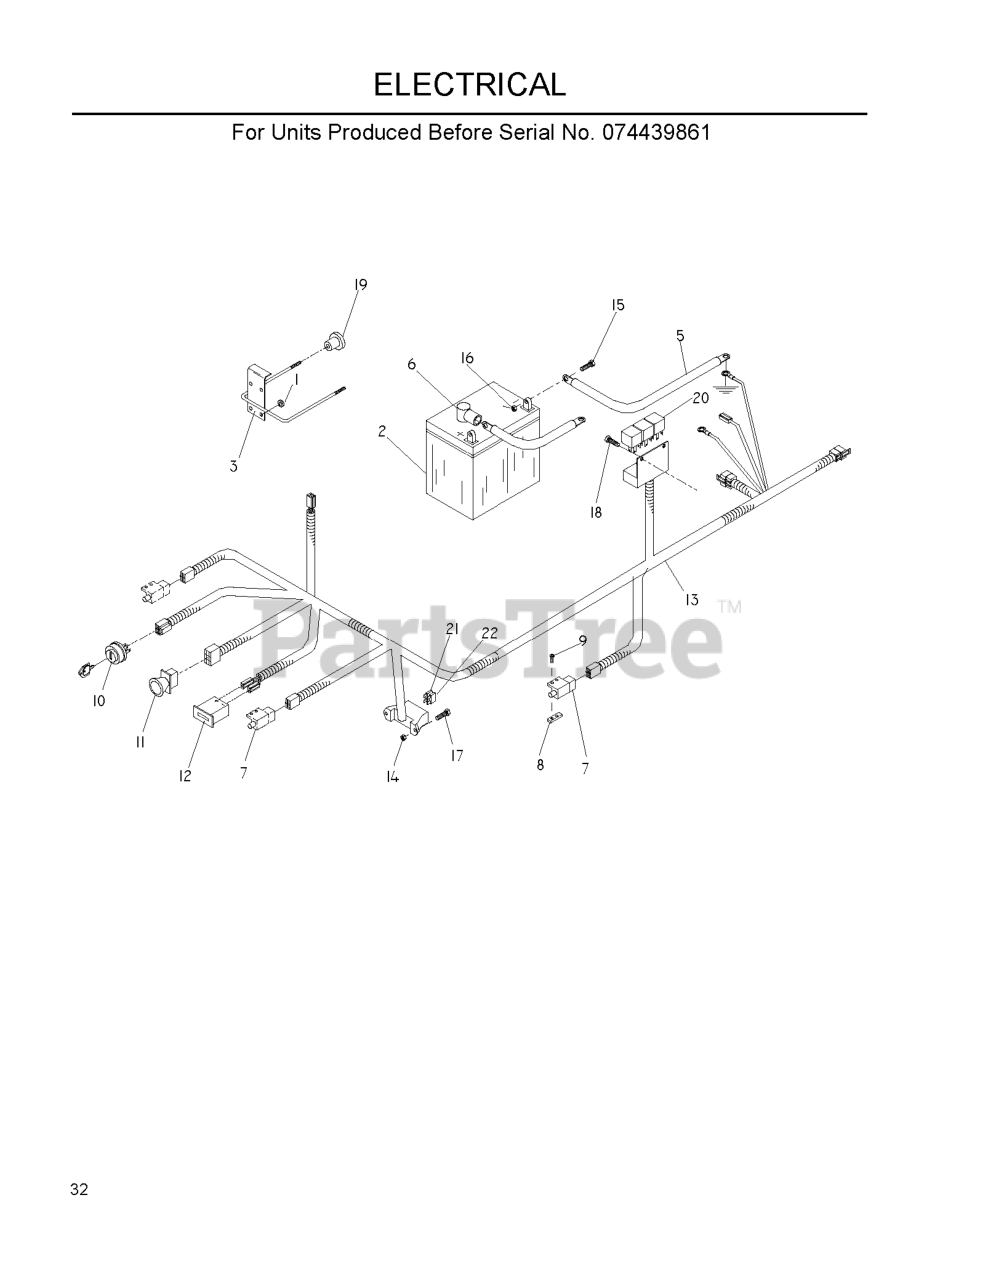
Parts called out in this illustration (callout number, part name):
1	GROMMET, BUMPER
2	BATTERY, 12 V 330 AMP
3	BATTERY HOLD DOWN
4	POST.CABLE LONG
5	CABLE-NEGATIVE
7	SWITCH, INTERLOCK
8	TAPPED PLATE
9	SCREW #10-24 X 5/8
10	RP IGNITION SWITCH
11	RP SWITCH.PTO.TERMINAL.STD.RED
12	HOUR METER
13	FRAME HARNESS
14	NUT 10-24 NYLOC
15	HCS 5/16C X 3/4
16	NUT 5/16 NYLOC
17	SCREW, #1--24 X 1/2 SLOTTED
18	SCREW #10 X 1/2 SELF TAPPING
21	FUSE, 7.5 AMP 32 VOLT ATO
22	FUSE, 20 AMP 32 VOLT ATO
